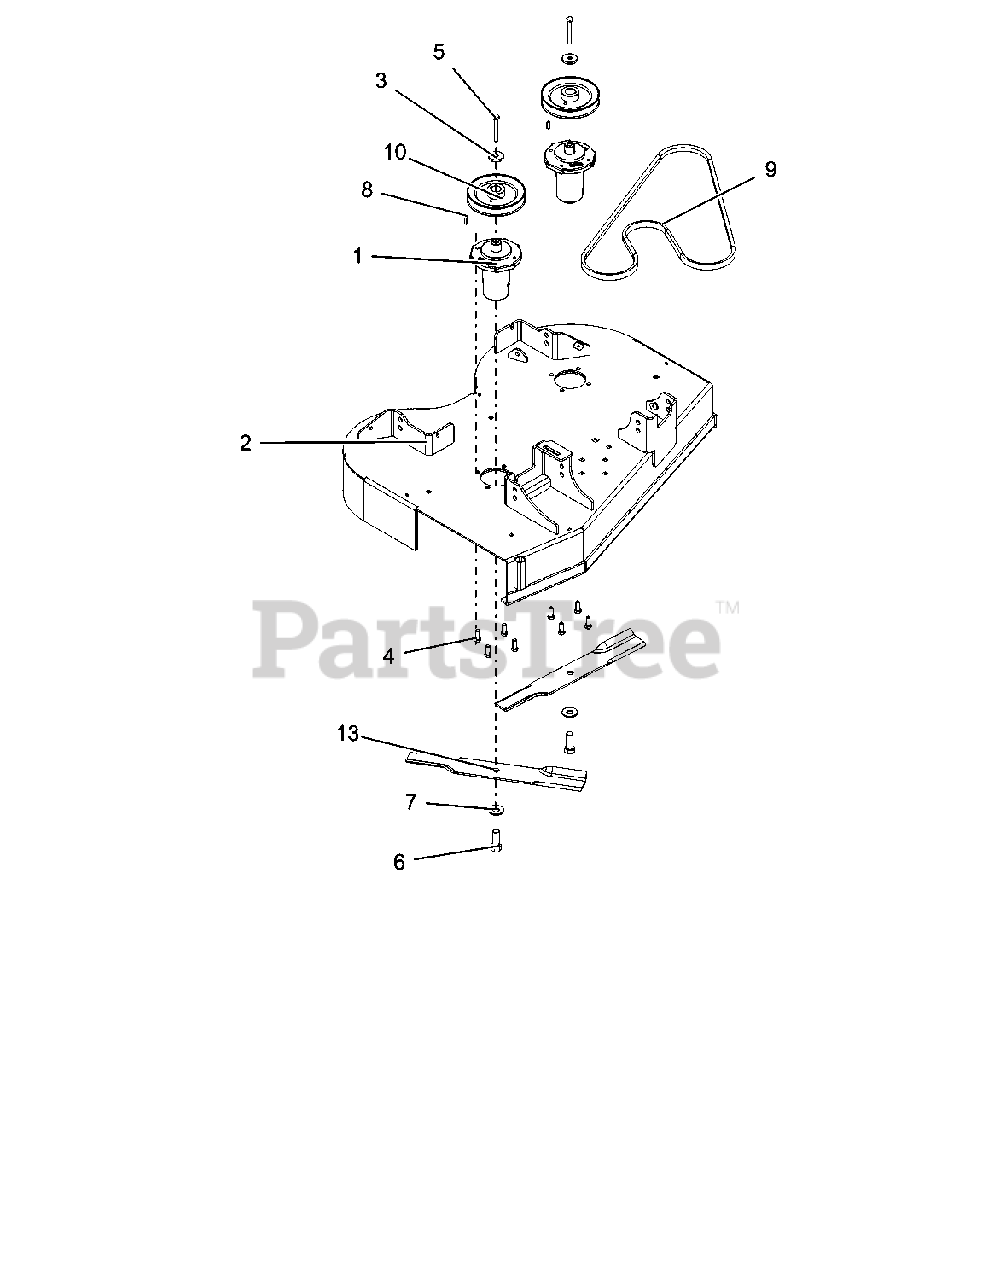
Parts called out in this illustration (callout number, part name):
1	ASM, MAINT FREE SPINDLE-SHORT
2	ASM, 36" DECK W/DECALS
3	RETAINER, SHEAVE
4	BLT-HEX .38-16X1.0 GR8 YZ EP30
5	BLT-HEX .38-16X2.75 GR8 YWZC
6	BLT-HEX .62-18X1.75 GR8 YWZC
7	WSHR-BLVL .669X1.535X.138
8	KEY-STR .25X.75X.25
9	BELT, 5L
10	PULLEY, V-1"ID X 5.75" OD
13	BLADE, 18.000 X .80 LIFT
